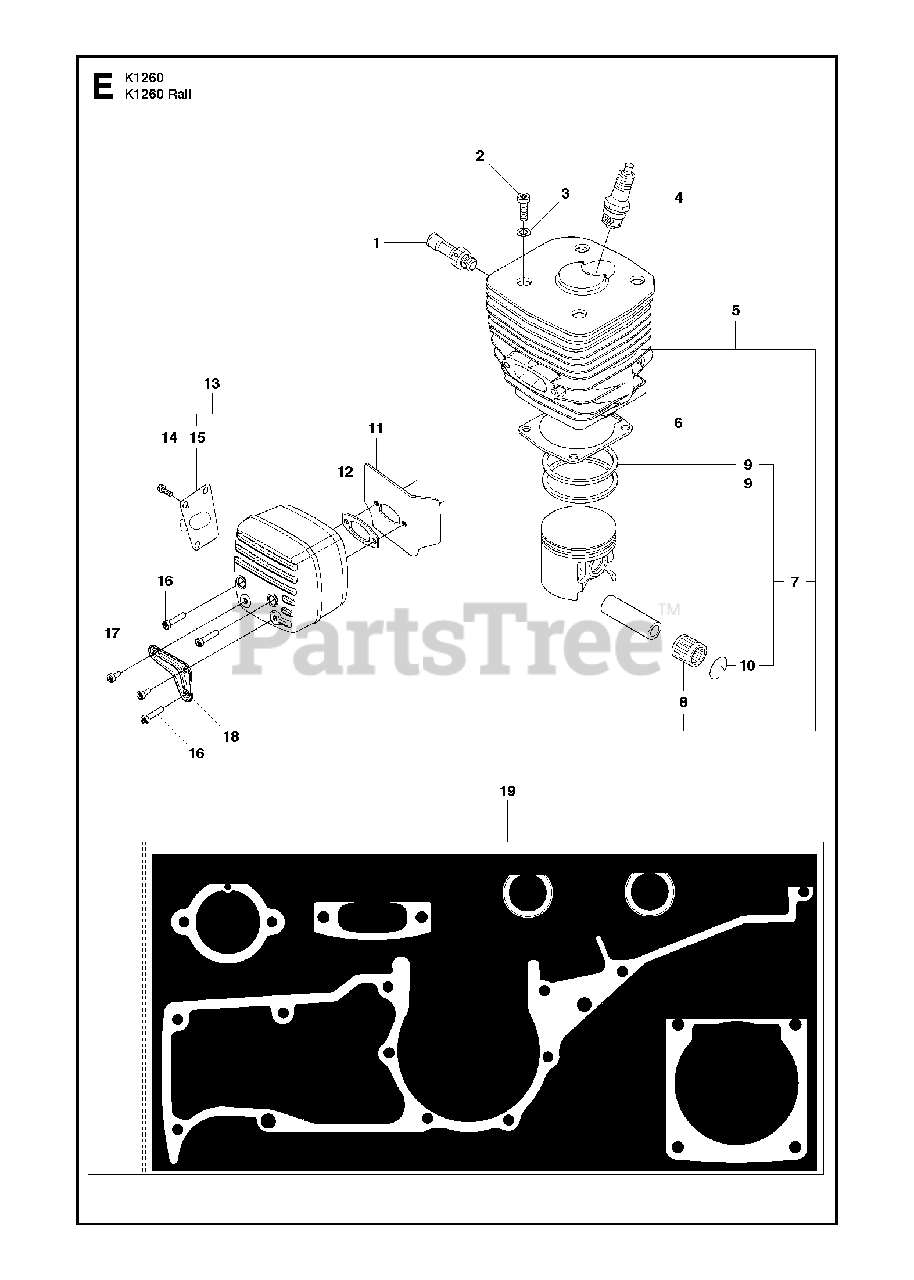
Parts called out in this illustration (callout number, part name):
1	DECOMPRESSION VALVE
5	CYLINDER ASSYIncl. 6 - 8
7	PISTON ASSYIncl. 9 - 10
8	NEEDLE HOLDER
11	COOLING AIR CONDUCTOR
13	MUFFLER ASSYIncl. 14 - 15
15	EXHAUST DUCT
16	SCREW ITXSCM
17	SCREW ITXSCM
19	GASKET KITIncl. 6, 12, 20 - 22
22	SEALING RING
